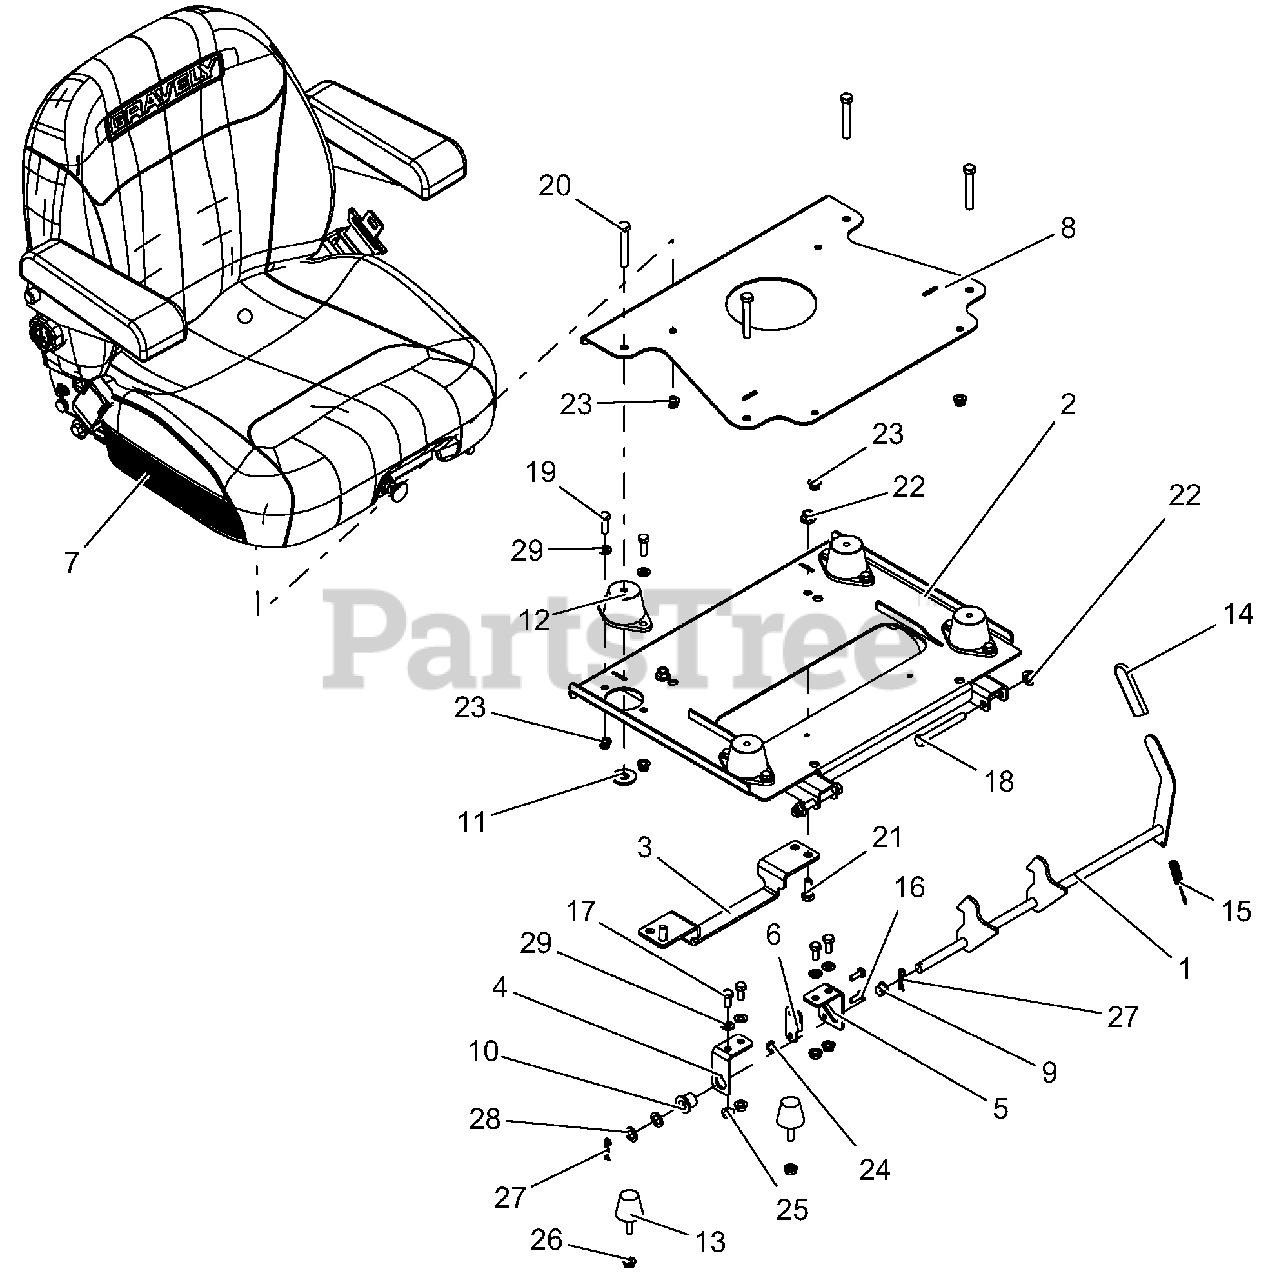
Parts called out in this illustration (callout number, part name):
1	WMT, SEAT LATCH
2	SEAT ISO MTG WMT W/SAFETY DECALS
3	BRKT, SEAT LATCH-BLACK
4	MOUNT, SEAT LATCH - RH
5	MOUNT, SEAT LATCH - LH
6	RETAINER-SEAT LATCH
7	SEAT, AIR SUSPENSION
8	WLDMT, SEAT MOUNTING
9	BUSHING, POLYLINER - .50 SPLIT
10	BSHG, FLANGE .515 X .750 X .745 X 1.00 NYLON
11	WLDMT, SEAT RETAINER
12	MOUNT, ISOLATOR
13	BUMPER, STUD MOUNTED CONE SHAPED
14	GRIP-VINYL-YELLOW .125 x 1.0 x 3.0
15	SPRG, EXTENSION
16	BLT-HEX .25-20X.75 GR5 YWZC
17	BLT-HEX .31-18X.75 GR5 YWZC
18	BLT-HEX .38-16X3.25 GR5 YWZC
19	BLT-HEX .31-18X1.00 GR5 YWZC
20	BLT-HEX .38-16X2.50 FTH GR5 YWZC
21	BLT-HEX .38-16X1.00 GR5 YWZC
22	NUT-LK-NYL-FLG .38-16 YWZC
23	NUT-LK-NYL-FLG .31-18 YWZC
24	NUT, LK-TOP-FLG .25-20 YWZC
25	NUT, LK-TOP-FLG .312-18 YWZC
26	@NUT-SPNLK-FLG .312-18 YWZC
27	PIN-HAIR INT .08X.38X1.42 YWZC
28	WSHR-FL-STL .520X.827X.062 YWZC
29	WSHR-FL-STL.344X.688X.065YWZC
